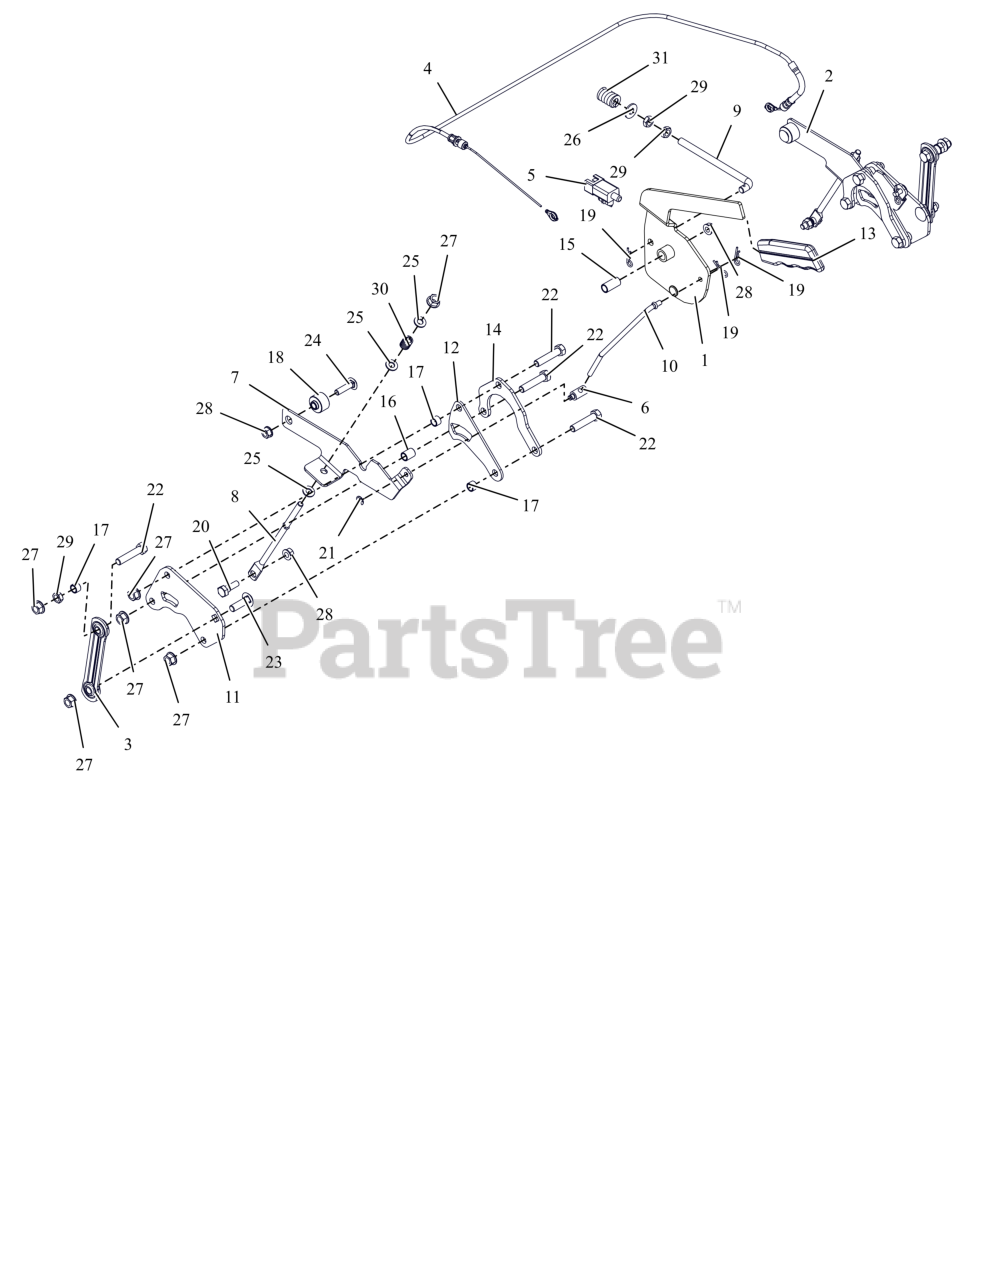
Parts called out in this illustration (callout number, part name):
1	LEVER, PARKING BRAKE
2	ARM, BRAKE - LH (W/PIN)
3	LINK, STAMPED STEERING
4	CABLE, BRAKE - PARKING
5	SWITCH, SNAP IN - N.O./N.O.
6	TRUNION, 1/4-20
7	ARM, BRAKE-RH
8	ROD, LINK - TRANSMISSION BRAKE
9	ROD, OVER CENTER
10	ROD, BRAKE LINK
11	BRKT, TRANSAXLE STEERING
12	BRKT-SPACER
13	GRIP, PARKING BRAKE (YELLOW)
14	PLATE, REAR REINFORCING
15	BSHG-SLV .385X.500X1.045
16	SPCR, SLV .385X.500X.652
17	SPCR, SLV .385X.500X.350
18	SPCR, FLANGE
19	PIN, HAIR #213 .08X1.19 ZCC
20	BOLT,SHLDR .38X.25 -.31-18X.75
21	RG-RTNG-EXT .250X.025
22	BLT, HEX .38-16X1.75 G5 ZCC
23	BLT,RHSSN .38-16X1.25 G5 ZCC
24	BLT, RHSSN.31-18X1.25 G5 ZCC
25	WSHR,FLT .344X.688X.065 ZCC
26	WSHR,FLT .375X.875X.083 ZCC
27	NUT-LK-TOP-FLG .38-16 ZC120
28	NUT-LK-TOP-FLG .312-18 GF ZCC
29	NUT-JAM .375-16 G2 ZCC
30	SPRING, COMPRESSION
31	SG-COMP .187X.56X1.62
